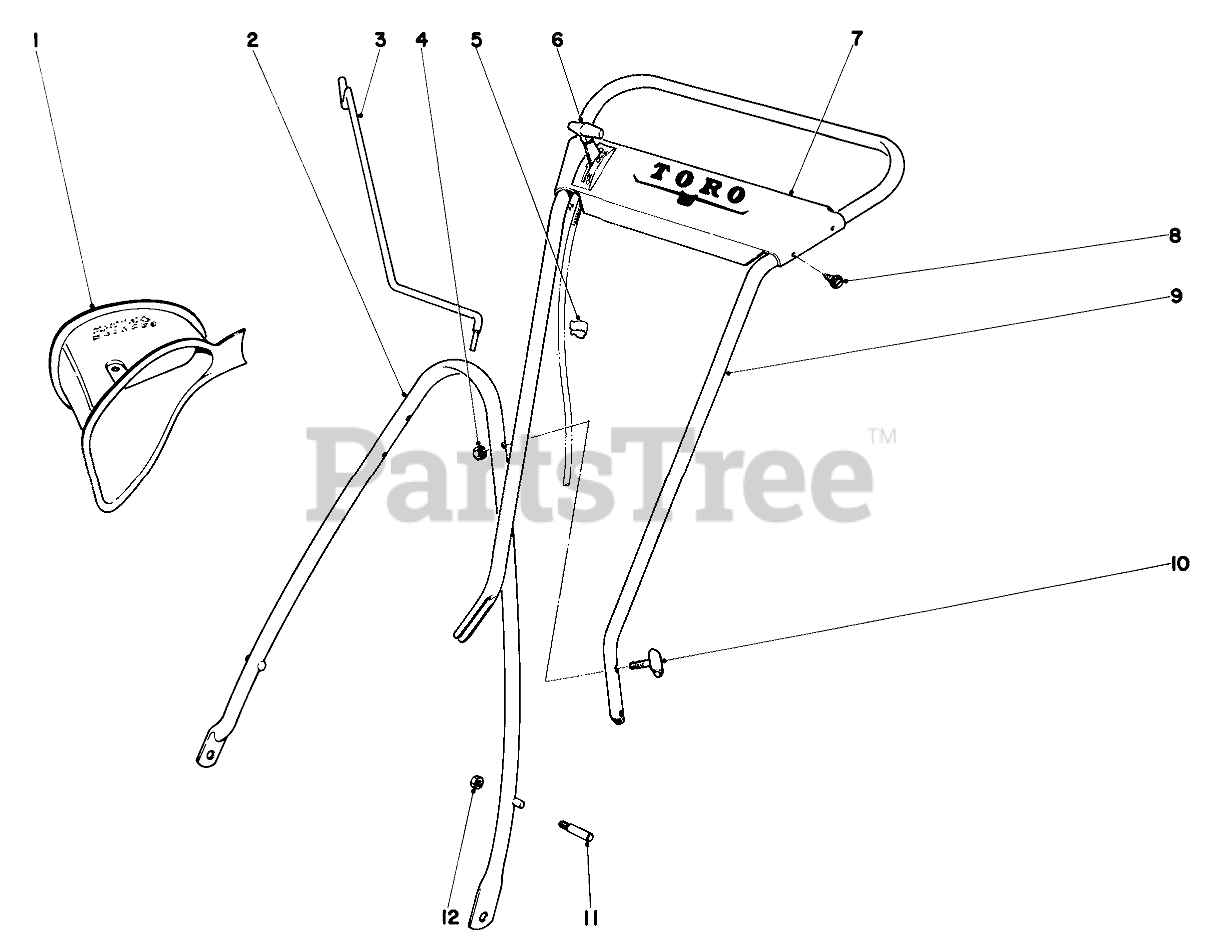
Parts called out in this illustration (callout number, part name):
1	Attachment Bag
2	Handle-Lower
3	GRASS BAG HANGER
4	Nut
5	CONTROL WIRE CLIP
6	Throttle Control
7	Escutcheon
8	SCREW-HWHTF
9	Handle-Upper
11	Handle Pin
12	Nut
